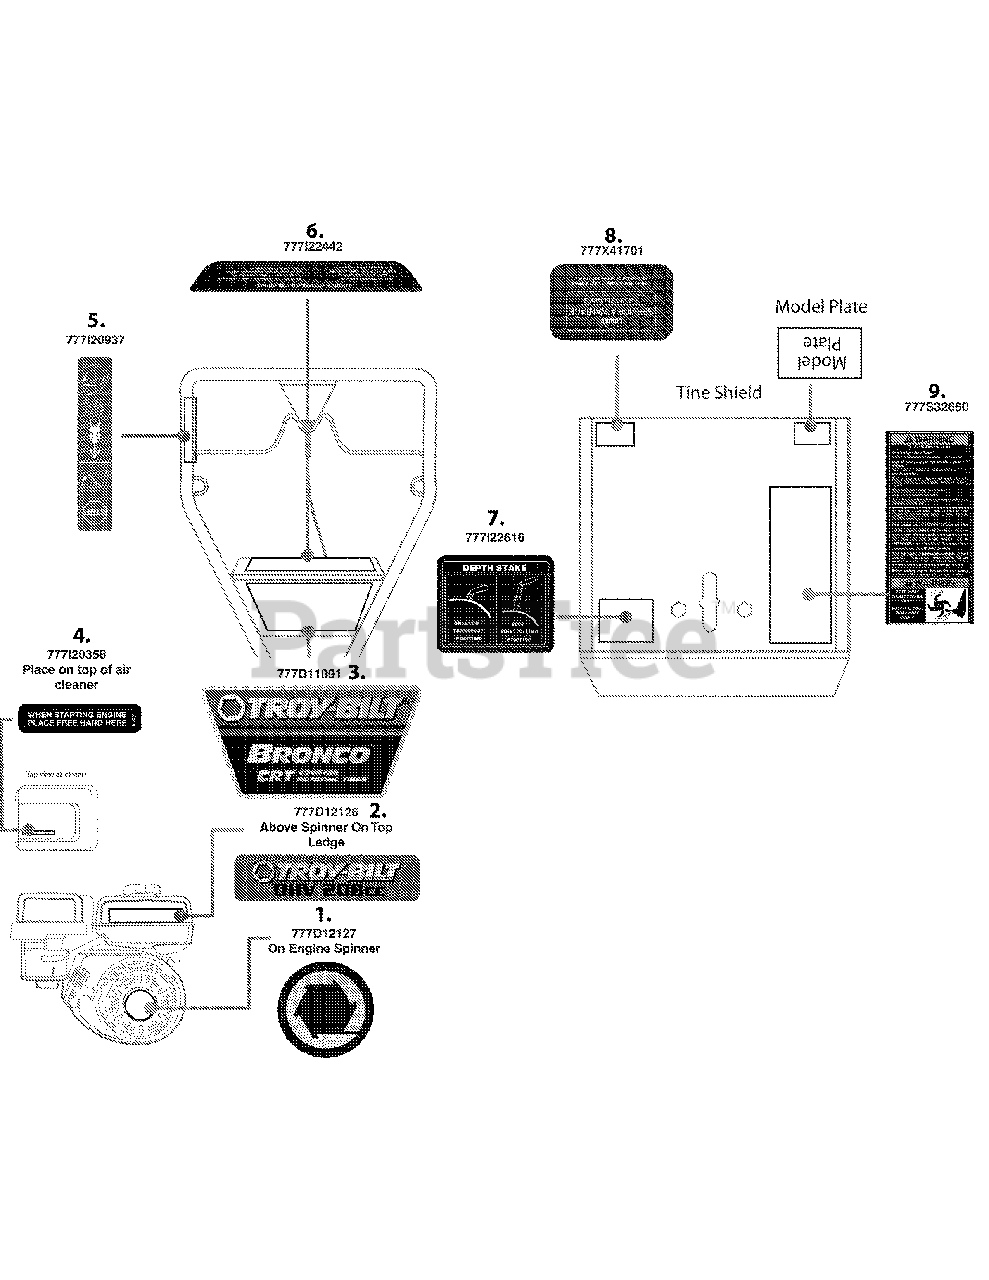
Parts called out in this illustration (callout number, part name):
1	LABEL-TILLER MTD ENGINE
2	LABEL-TILLER MTD ENGINE TROY
3	LABEL-TILLER HANDLE BRONCO CRT
4	LABEL-PLACE HAND HERE
5	LABEL-BAIL CONTROL
6	LABEL-HANDLE PANLE
7	LABEL:TILLER TINE SHIELD DEPTH
9	LABEL:TILLER TINE SHIELD
